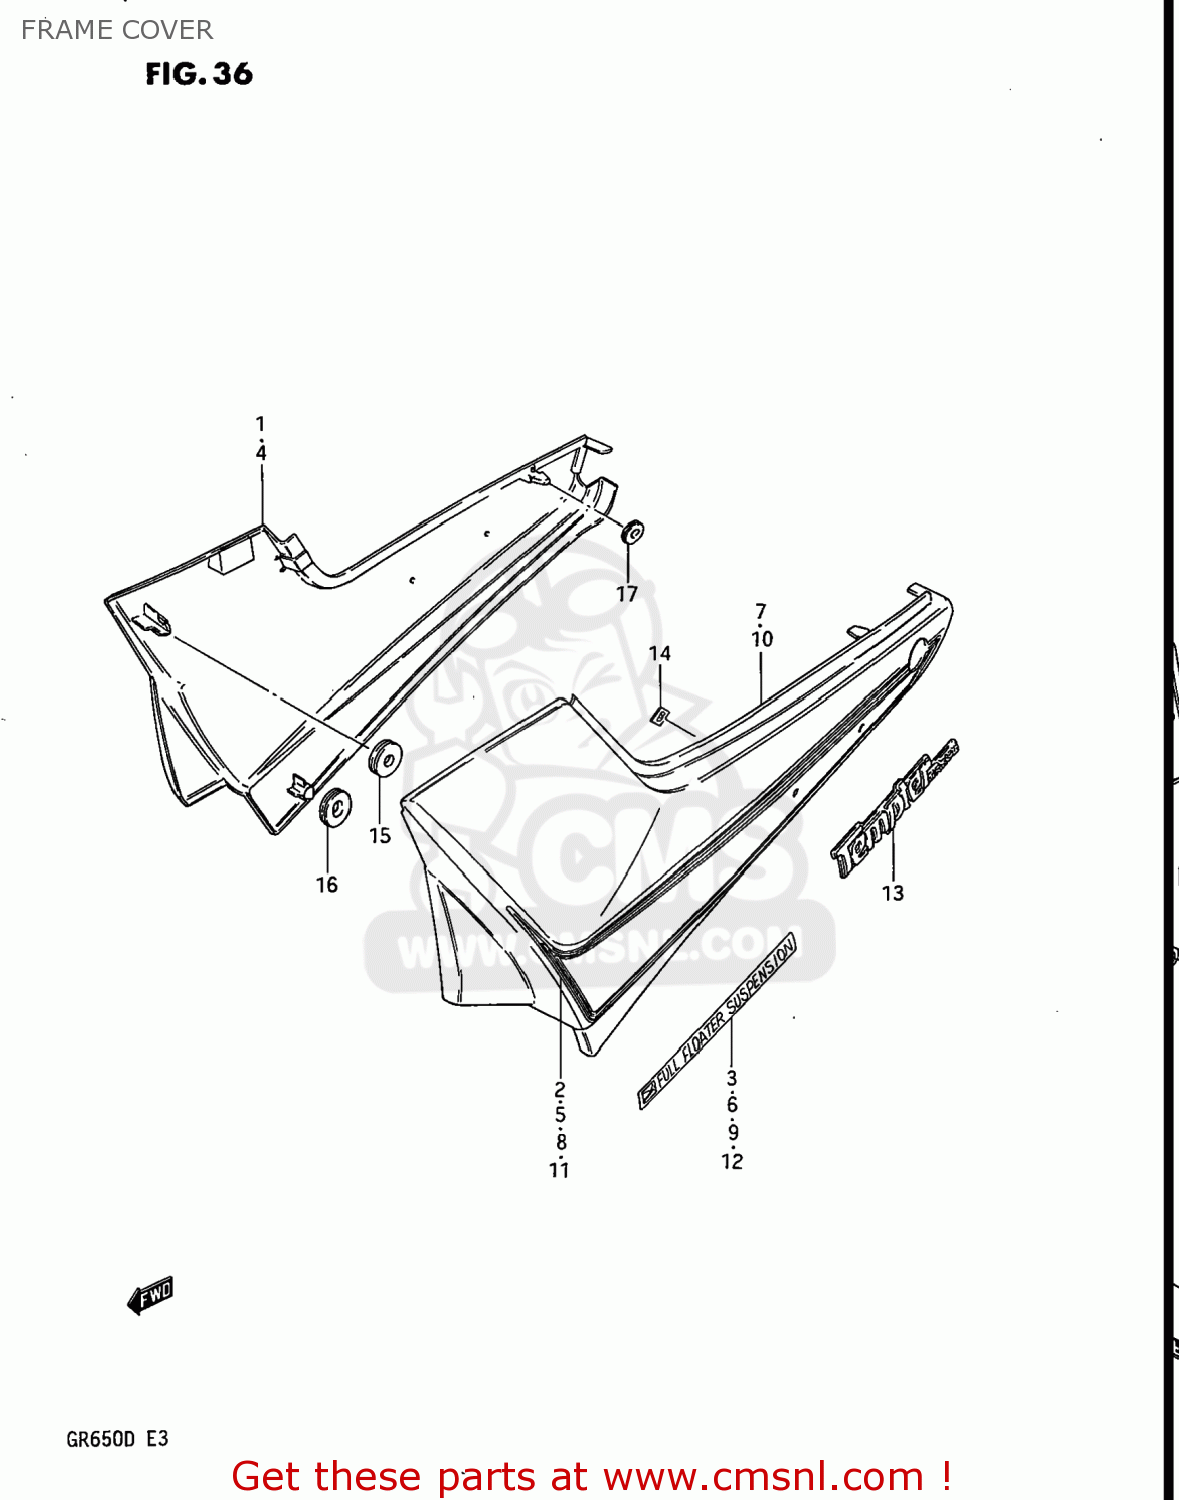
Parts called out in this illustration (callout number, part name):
1	COVER ASSEMBLY,FRAME,RIGHT
2	TAPE SET,FRAME COVER,RIGHT
3	EMBLEM
4	COVER,FRAME,RIGHT
5	TAPE SET,FRAME COVER
6	EMBLEM
7	COVER ASSEMBLY,FRAME,LEFT
8	TAPE, LH
9	EMBLEM
10	COVER,FRAME,LEFT
12	EMBLEM
13	EMBLEM,FRAME COVER
14	NUT
15	CUSHION
16	CUSHION
17	CUSHION
